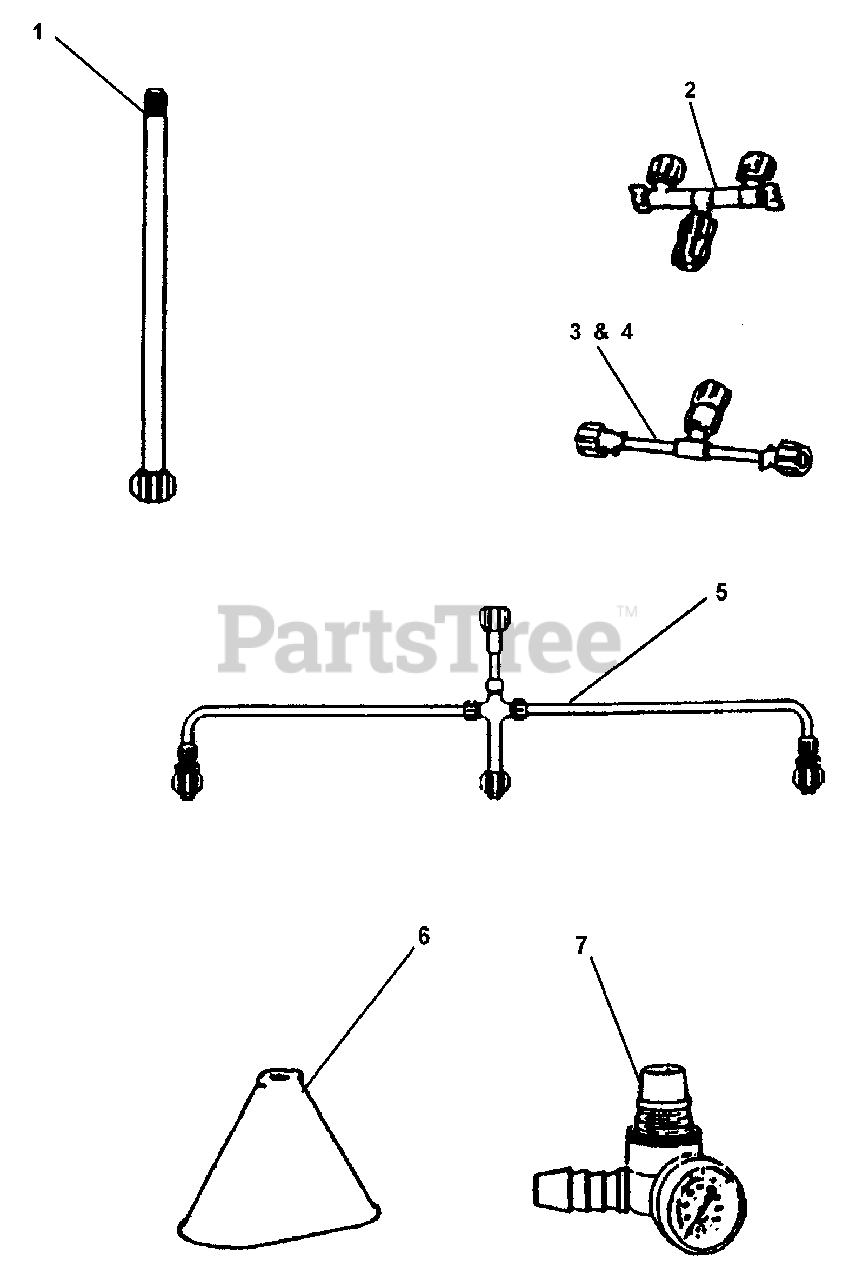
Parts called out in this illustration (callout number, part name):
1	5' LANCE EXTENSION
2	NOZZLE, DUAL SWIVEL
3	TWIN NOZZLE ASSY - 6"
4	TWIN NOZZLE ASSY - 11"
5	3 NOZZLE SPRAY BOOM
6	WEED SHIELD
7	ADJ. PRESSURE REGULATOR
